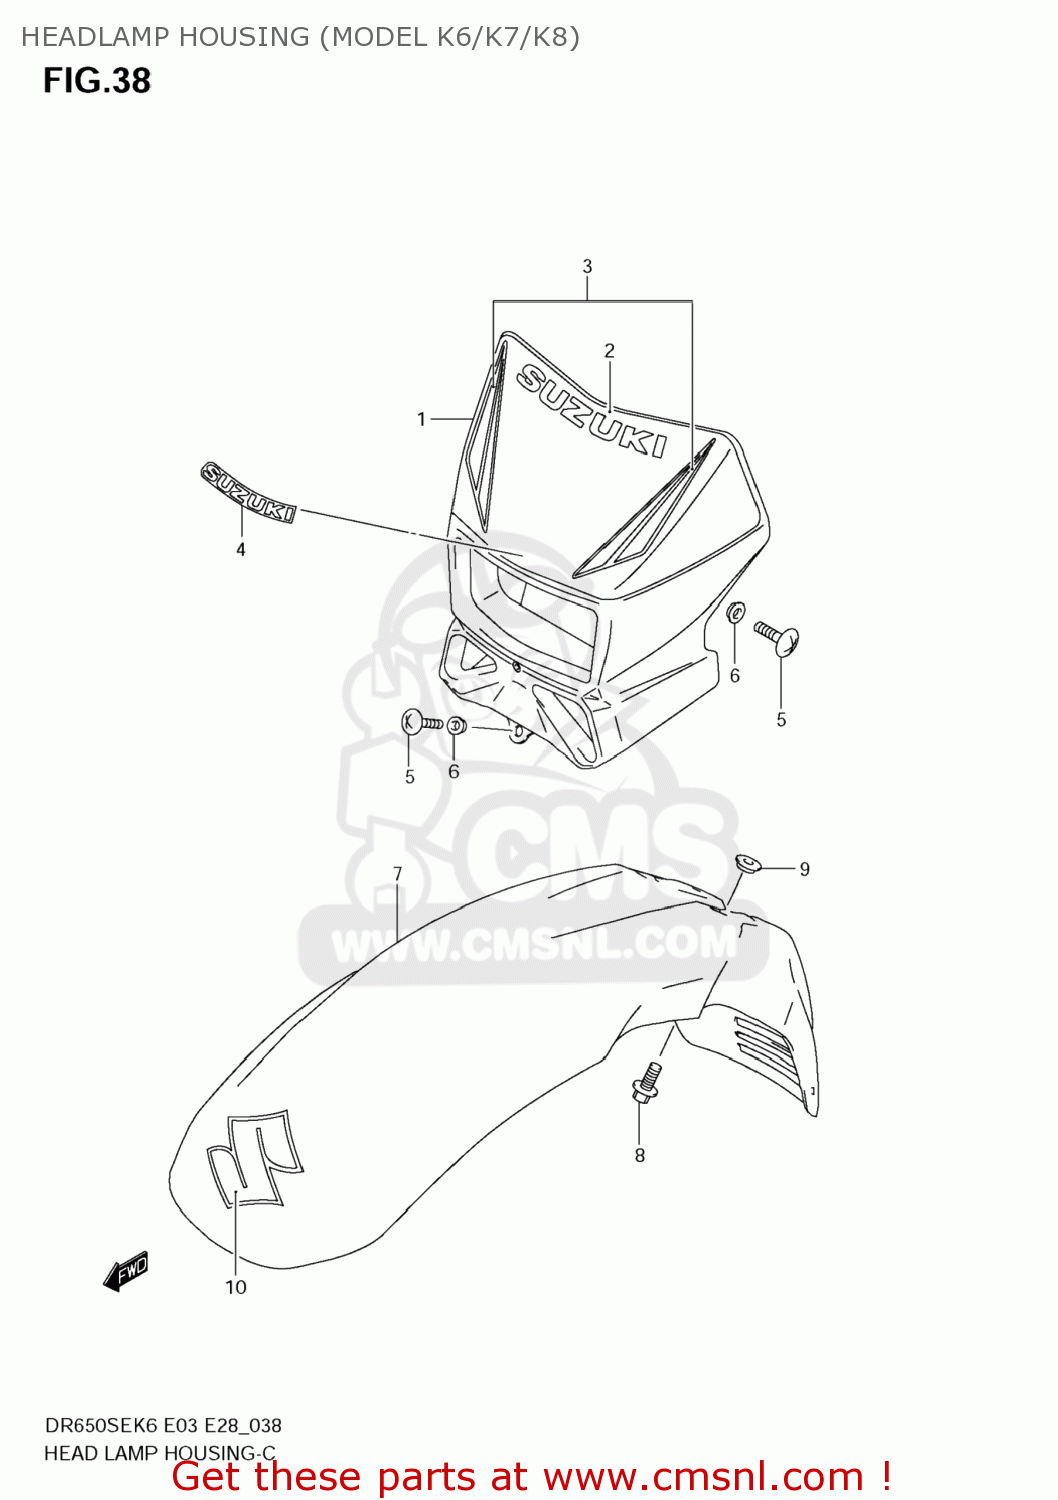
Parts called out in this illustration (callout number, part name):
1	COVER,HEADLAMP
2	TAPE,HEADLAMP HOUSING
3	TAPE SET,HEADLAMP HOUSING
4	EMBLEM,SUZUKI
5	SCREW
6	WASHER
7	FENDER,FR
8	BOLT(6X16)
9	WASHER
10	EMBLEM,S
